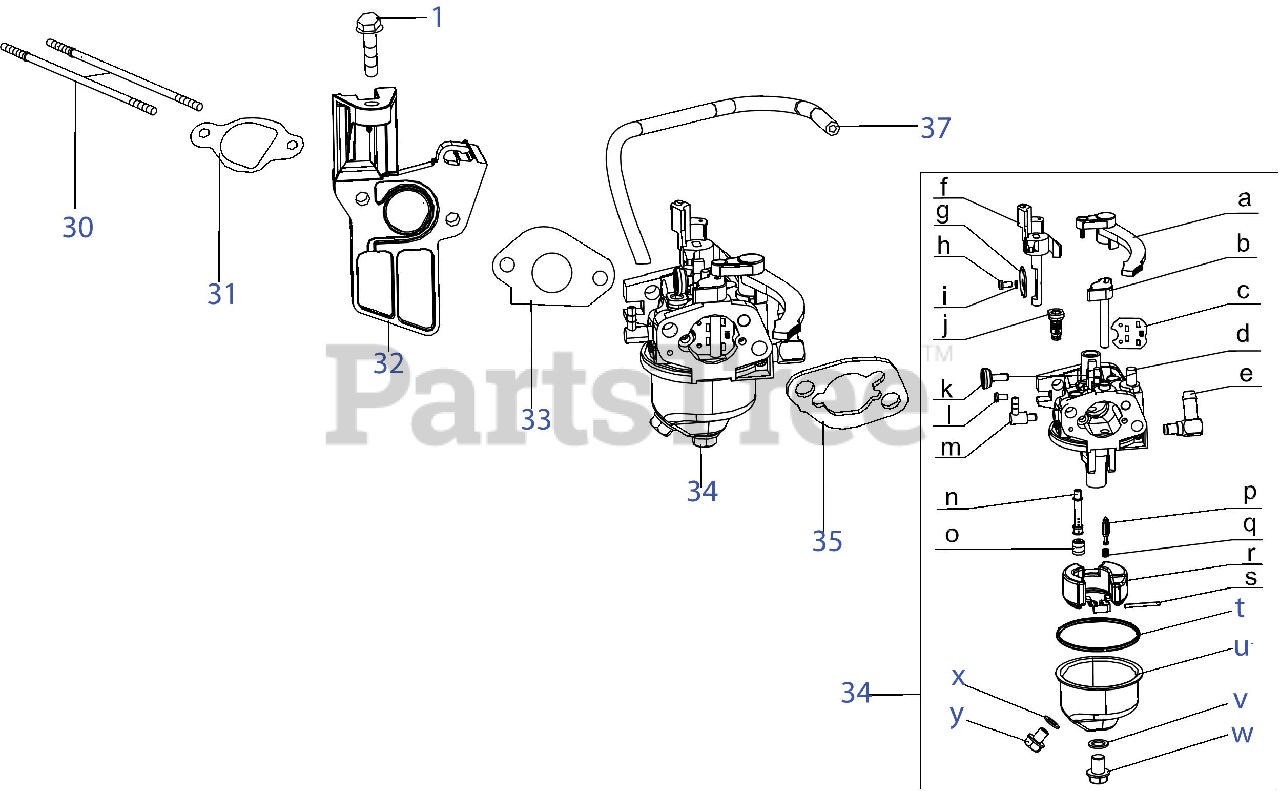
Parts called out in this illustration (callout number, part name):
1	Bolt M6x16
30	Stud M6x110
31	Gasket, Carburetor Insulator
32	Carburetor Insulator
33	Carburetor Gasket
34	Carburetor
35	Gasket,Air Cleaner
37	Fuel Hose 3.2x6.5x240
